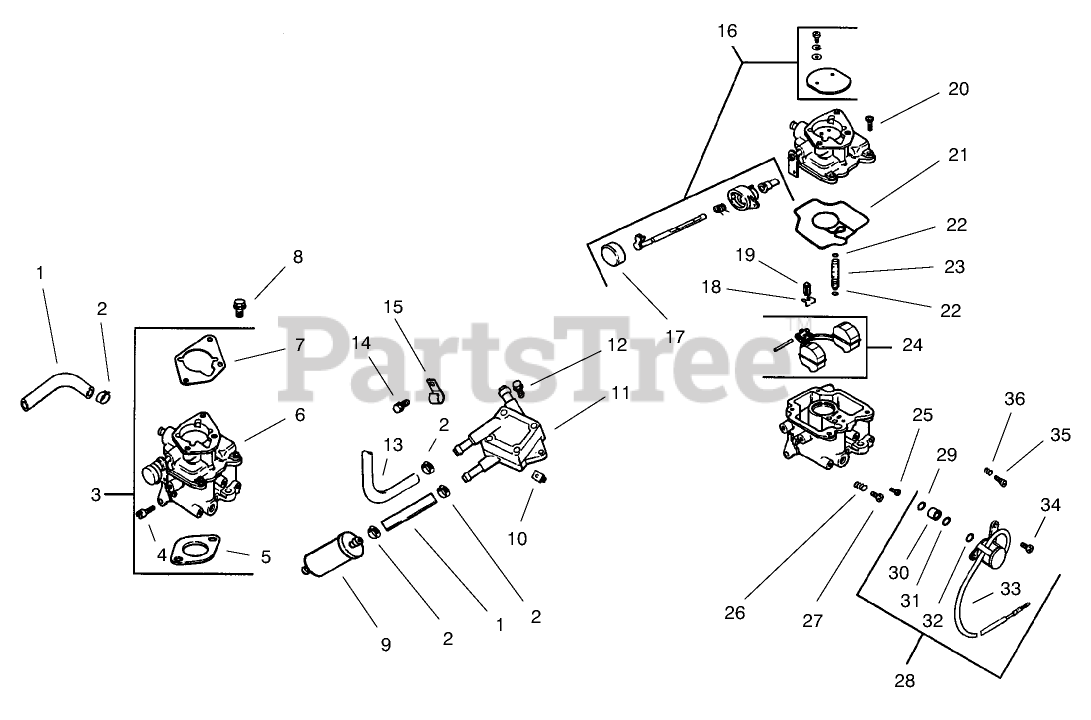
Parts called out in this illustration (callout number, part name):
1	Line-Fuel
2	Clamp
3	Kit, carburetor w/gasket (Includes 4-7)
4	Screw-Throttle Stop
5	Gasket-Air Cleaner
6	Carburetor assembly (Includes 15-35)
7	Gasket-Carburetor
8	Screw
9	Filter-Fuel
10	Nut
11	Pump-Fuel
12	Screw
13	Line, fuel17"
14	Screw
15	Clip-Cable (Only On: 72103)
16	Kit-Choke Repair (Incl. Ref. #33
17	Cap-Choke Lever Carburetor Assembly (Incl. Ref. #1-25 32)
18	Clip-Inlet Needle Valve
19	Valve-Inlet Needle
20	Screw
21	Gasket-Carburetor Body
22	ORing
23	Jet-Slow
24	Kit-Float Repair
25	Jet-Main
26	Spring-Idle Speed Adjust
27	Screw-Idle Speed Adjust
28	Kit-Solenoid Assembly
29	ORing
30	Seat-Solenoid
31	ORing
32	ORing
33	Solenoid
34	Screw
35	Needle-Idle Adjust
36	Spring-Idle Adjust
